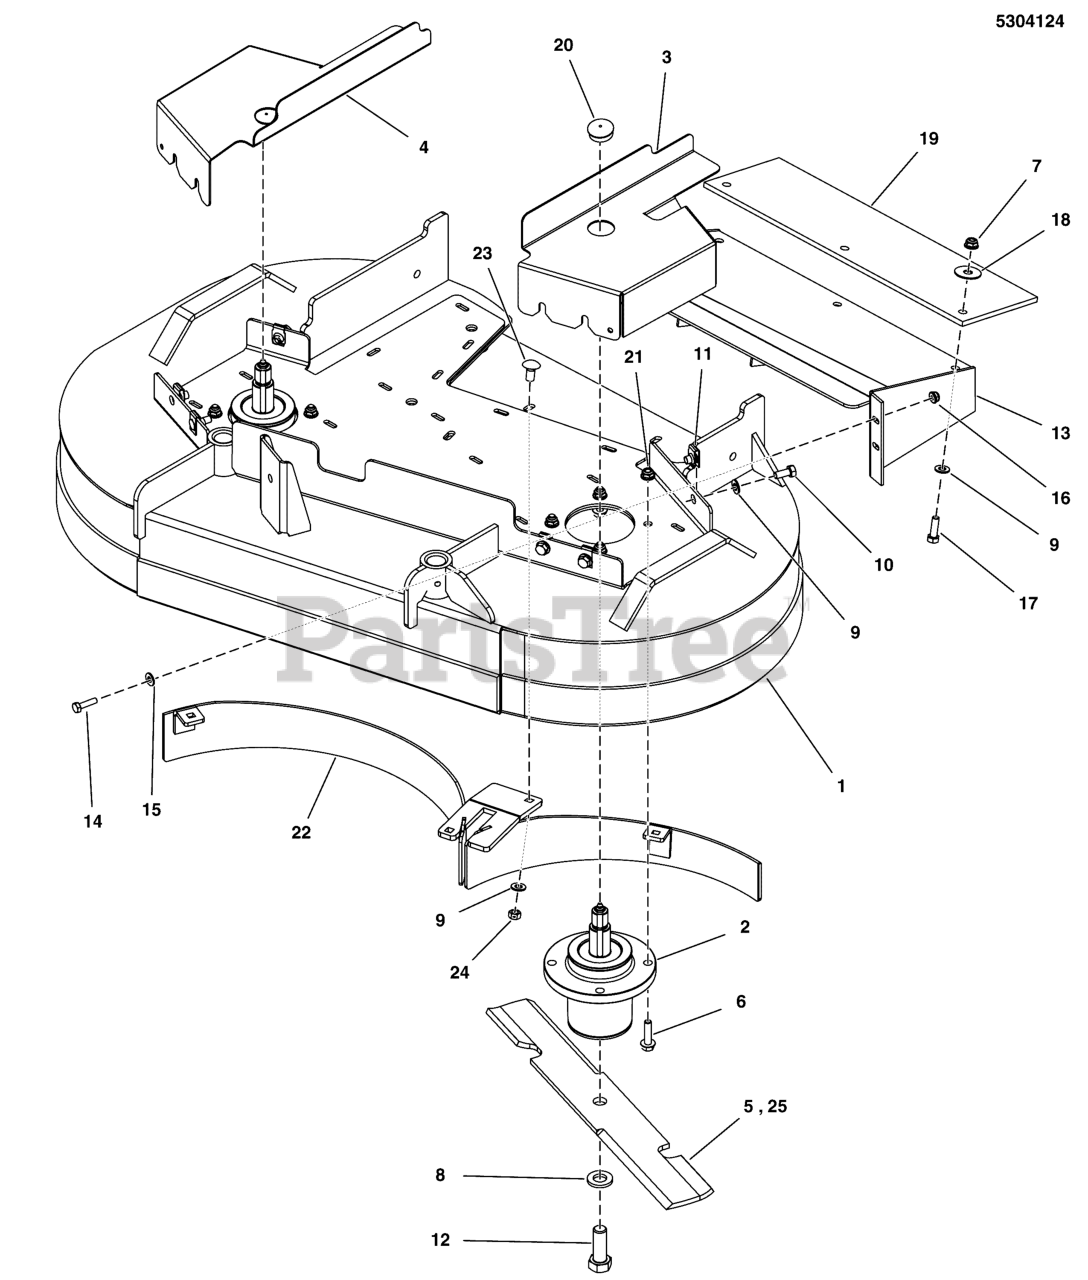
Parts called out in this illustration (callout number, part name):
1	DECK SHELL W/ DECALS, 36RDCE, FW25 (5413552B)
2	SPINDLE, ASSM, ALUMINUM - 5.25
3	GUARD, DECK SPINDLE FW2536RDCE, LH - RED
4	GUARD, DECK SPINDLE FW2536RDCE, RH - RED
5	BLADE SET, 36 DECK (2)
6	BOLT, 3/8-16 X 1-1/4, FLANGE, GD5, CZ
7	NUT, 5/16-18 HEX NYLOCK FLANGE
8	WASHER, BLADE BOLT, 9/16" F436, CZ
9	WASHER, 5/16" SAE
10	BOLT, 5/16-18 X 3/4 GD5
11	BODY CLIP, 5/16-18-7GA MATERIAL
12	BOLT, 5/8-11 X 1-3/4 GD8
13	WELD, DISCHARGE CHUTE, FW25 36RD - BLK
14	BOLT, 1/4-20 X 3/4 GD5 CZ
15	WASHER, 1/4 SAE
16	NUT, 1/4-20 HEX NYLOCK FLANGE
17	BOLT, 5/16-18 X 1 GD5 CZ
18	WASHER, 5/16 FENDER
19	FLAP, RUBBER, 36RD
20	PLUG, PANEL, 1.25 - BLACK
21	NUT, 3/8-16 HEX NYLOCK FLANGE
22	WELD, REAR BAFFLE, 36RD, SHORT - BLK
23	BOLT, 5/16-18 X 3/4, CARRIAGE
24	NUT, 5/16-18, HEX, CNTR LK,ZINC PHOS/OIL
25	BLADE SET, MULCH, 36 DECK (2)(SET OF 2)
